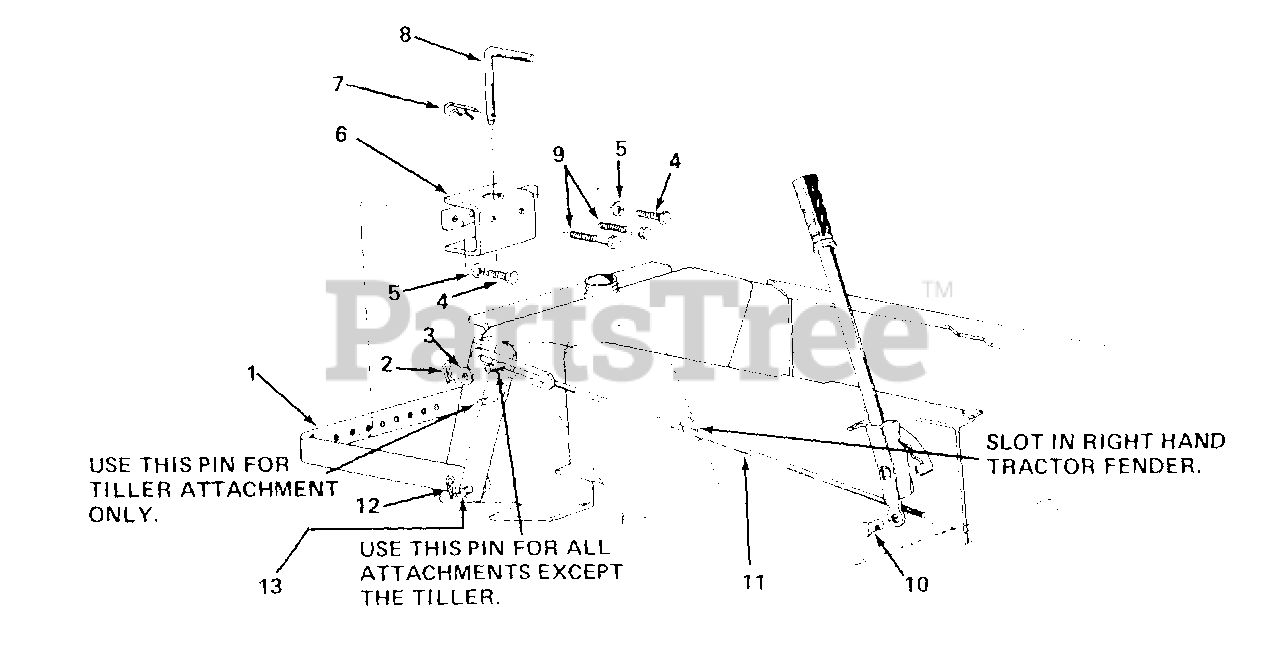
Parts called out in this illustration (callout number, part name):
3	Fl-Wash. 1/2" I.D.
4	Hex Bolt 1/2-13 x 1.0" Lg.
5	L-Wash. 1/2" I.D.
8	Hitch Pin
9	Hex Bolt 1/2-13 x 3.0" Lg.
10	Adjustment Ferrule
13	Hitch Rod
